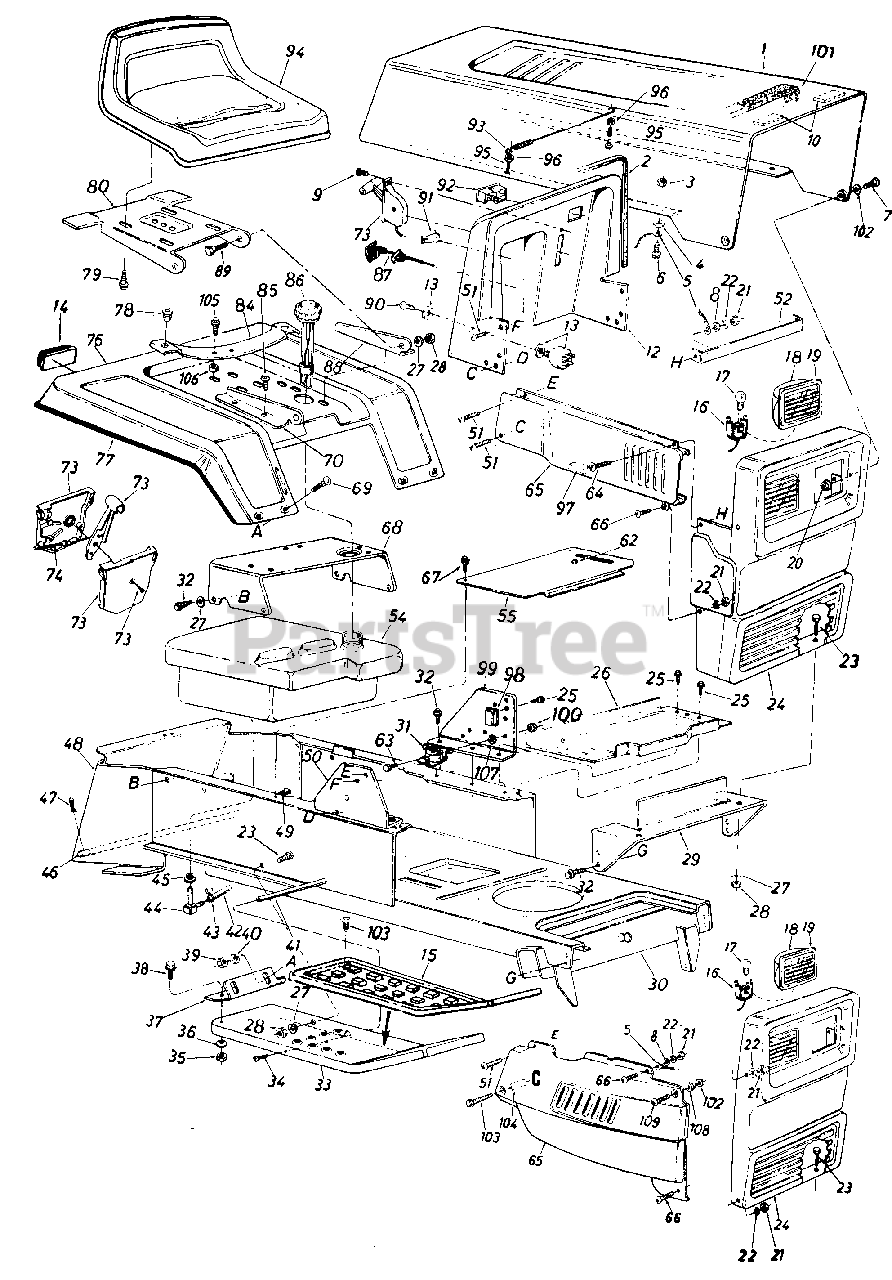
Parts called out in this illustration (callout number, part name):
1	Hood
2	Vinyl Molding Strip-31" Lg.
3	Hex Sems Nut #10-24 Thd.
4	Fl-Wash. .20" I.D. x .41" O.D.
5	Hood Stop
6	Truss Hd. Mach. Scr. #10-24 x.50" Lg.*
7	Shld. Bolt .375 Dia. x .125t
8	Fl-Wash. 1/4" I.D.*
9	Truss Mach. AB-Tap Scr. #10-24 x .5" Lg.
10	Foam Strip
12	Dash Ass'y.
13	Ignition Switch
14	Reflector
15	Rubber Foot Pad
16	Socket
17	Lamp
18	Headlight Housing
19	Lens
20	L-Nut 1/4-28 Thd.
21	Hex Nut 1/4-20 Thd.*
22	L-Wash. 1/4" I.D.*
23	Hex Bolt 5/16-18 x .75" Lg.*
24	Grille
25	Hex Wash. Hd. AB-Tap Scr. 1/4 x.50" Lg.
26	Battery Plate
27	L-Wash. 5116" I.D.*
28	Hex Nut 5/16-18 Thd.*
29	Grille Mounting Bracket
30	Lower Frame Ass'y.
31	Solenoid
32	Hex Thd. Rolling Scr. 5/16-24 x .75" Lg.
33	Running Board-R.H.
34	Truss Mach. Scr. 5/16-18 x .75" Lg.*
35	Hex Nut 5/16-18 Thd.*
36	Bell-Wash. .34" I.D.
39	Hex Nut 1/4-20 Thd.*
40	L-Wash. 1/4" I.D.*
41	Running Board Rod
42	Fuel Line 44" Lg.
43	Hose Clamp 3/8"
44	90ø Elbow
45	Bushing
46	Hitch Rod
47	Internal Cotter Pin
48	Hitch Plate
49	Speed Nut
50	Dash Support Brkt.-R.H.
51	Hex Wash Hd. Tap Scr. 1/4 x .75" Lg.
52	Tie Strap-Grille Side Panelt
54	Fuel Tank
55	Transmission Cover Ass'y.
62	Snap Bushing
63	Hex Bolt 1/4-20 x .50" Lg.*
64	Truss Hd. Scr. 1/4-20 x .75"*
66	Truss Mach. Scr. 1/4-20 x .50" Lg.*
67	Truss Mach. B-Tap Scr. #10 x.50" Lg.
68	Seat Mounting Channel
69	Carriage Bolt 1/4-20 x .50"*
70	Seat Bracket-R.H.
73	Throttle Control Box Ass'y.
74	Throttle Control Wire
78	Grommet
79	Hex Wash. Hd. AB-Tap Scr. 3/8 x .75" Lg.
80	Seat Pivot Bracket
84	Seat Spring
85	Hex Wash. Hd. Self-Tap Scr. 5/16-18 x .50" Lg.
86	Gas Cap w/Gauge
87	Choke Control Comp.
88	Seat Bracket-L.H.
89	Shld. Bolt .437" Dia. x .162"
90	Ignition Key
91	Light Switch
92	Ammeter
93	Hood Spring
94	Seat Ass'y.
95	Hex Bolt #10-24 x 1.0" Lg.
96	Hex Sems Nut #10-24
97	Rubber Strip 1/2" Sq, x 21/2"
98	Circuit Breaker
99	Dash Support Brkt.-L.H.
100	Hex Sems Nut 1/4-20 Thd.
101	PVC Foam
102	Washer .34" I.D. x .62" O.D.
103	Hex Hd. Tap Scr. 1/4-20 x 1.75" Lg.
104	Spacer .255" I D
105	Hex Tap Scr. 5/16-18 x 1.25"
106	Spacer .38" I.D.
107	Ext. L-Wash. 1/4" I.D.
108	Shld. Spacer .125" Lg
109	Truss Hd. Scr. 1/4-20 x 1"
